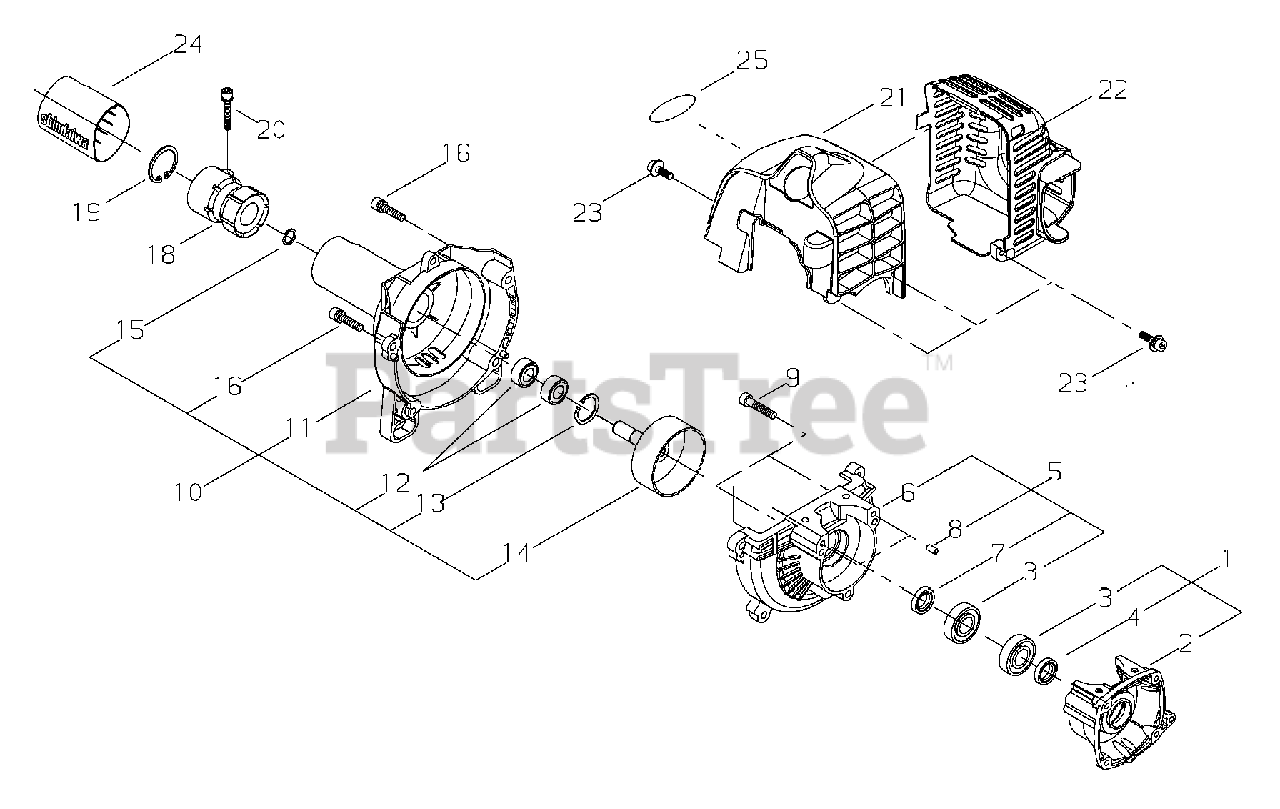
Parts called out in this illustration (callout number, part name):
1	CRANKCASE ASSY - REAR
2	CRANKCASE - REAR
3	BEARING, BALL - 6001C3
4	SEAL, OIL - 12
5	CRANKCASE ASSY - FRONT
6	CRANKCASE - FRONT
7	SEAL, OIL - 12
8	PIN - LOCATING
9	SCREW - 5X25
10	FAN CASE ASSY
11	CASE, FAN
12	BEARING, BALL - 6000
13	RING, RETAINING - 26
14	DRUM, CLUTCH
15	RING, RETAINING
16	SCREW - 5X16
18	CUSHION
19	RING, RETAINING - 40
20	SCREW - 5X22
21	COVER, ENGINE
22	COVER, EXHAUST
23	SCREW - 4X16
24	PROTECTOR
25	LABEL - MODEL 242
